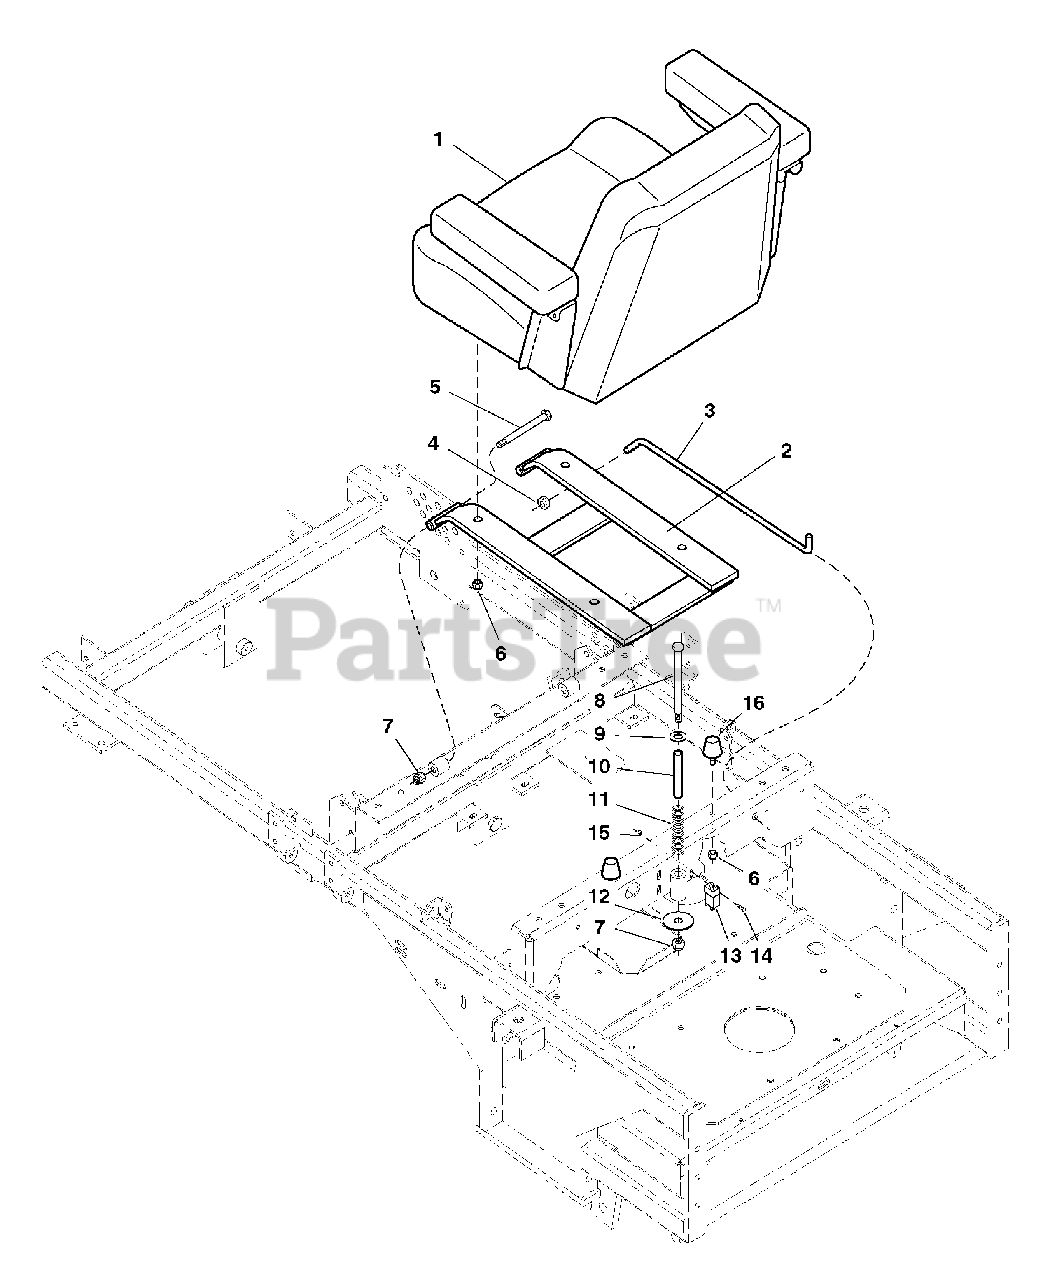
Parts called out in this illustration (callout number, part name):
1	SEAT, Brown (complete)
2	SEAT MOUNT
3	SEAT STOP ROD
4	COLLAR, 5/16 Set
5	CAPSCREW, Hex Hd, 3/8-16 x 4
6	NUT, Hex, Nylon Lock, 5/16-18
7	NUT, Hex, Nylon Lock, 3/8-16
8	CAPSCREW, Hex Hd, 3/8-16 x 6
9	WASHER, 3/8
10	SPACER, Seat Spring
11	SPRING, Compression
12	WASHER, 3/8 x 2
13	SWITCH, PLUNGER, N.O./N.C.
14	SCREW, #10-24 x 1
15	NUT, Hex, #10-24
16	RUBBER BUMPER
